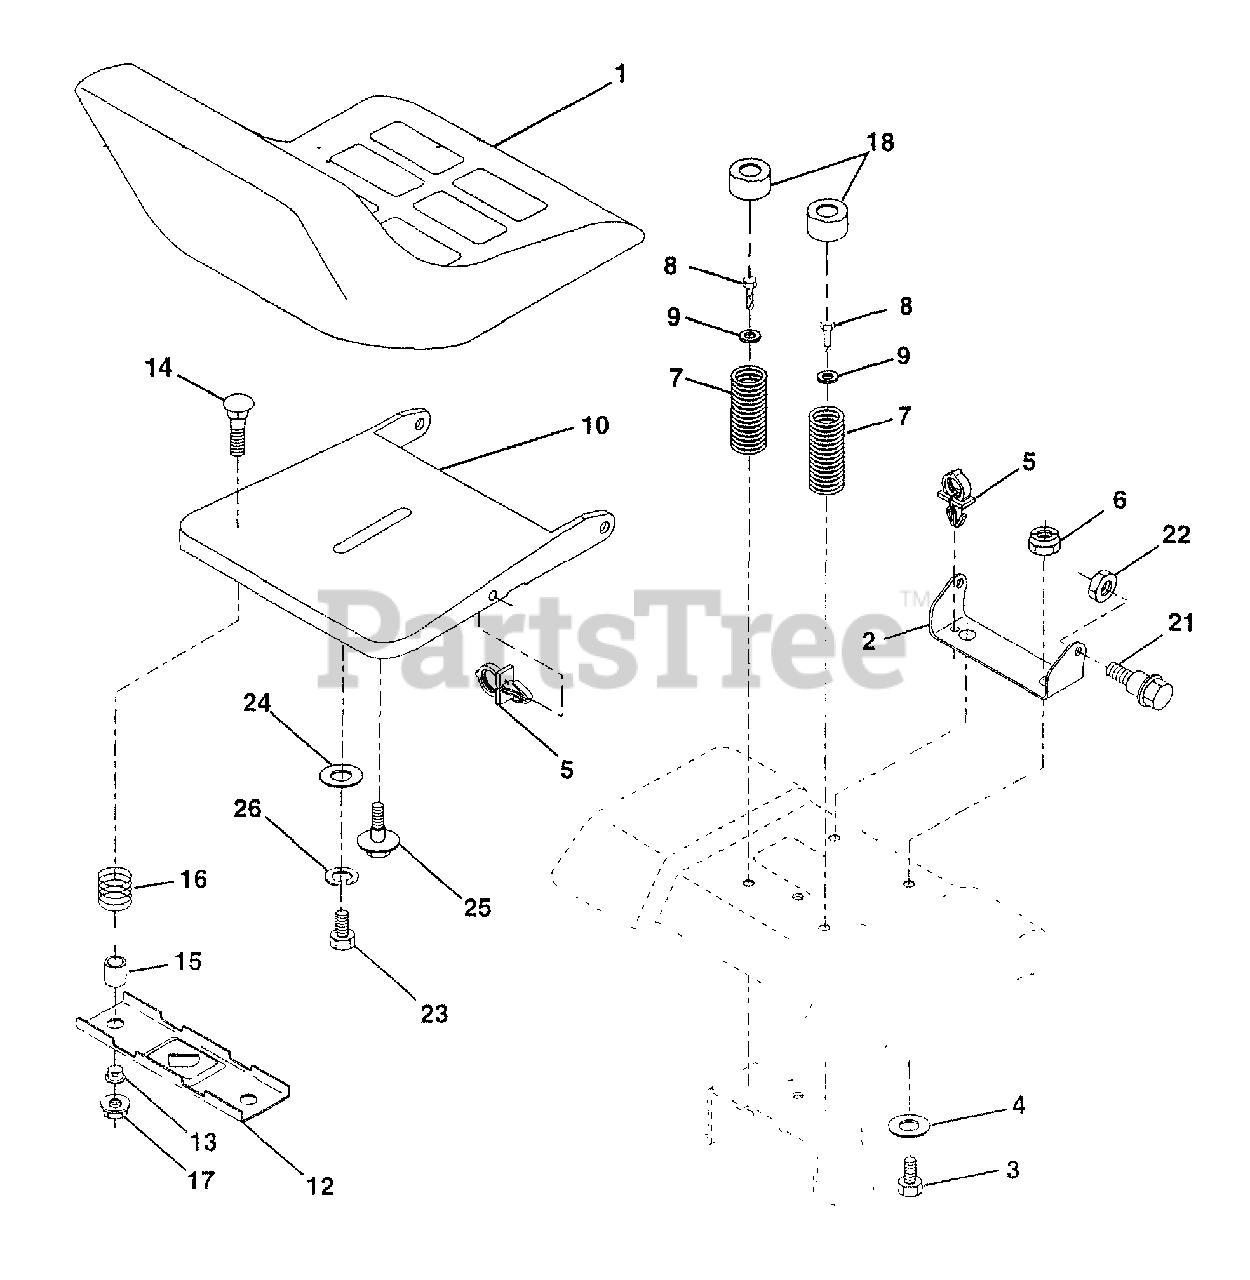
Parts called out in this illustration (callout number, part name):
1	Seat
2	Bracket Pivot Seat 8 720
3	Bolt Fin Hex 3/8-16unc X 1
4	Washer 13/32 X 1 X 10 Ga
5	Clip Push-In
6	Nut Hex w/Ins 3/8-16 Unc
7	Spring Seat Cprsn 2 250 Blk Zi
8	Screw Thdrol 3/8-16 X 1 Ty-tt
9	Washer 13/32 X 1 X 14 Ga.
10	Pan Seat
12	Bracket Mounting Switch
13	Bushing Snap Blk Nyl 50 Id
14	Bolt Rdhd Sqnk 1/4-20x1-3/8
15	Spacer Split 28 x 88 Zinc
16	Spring Cprsn Plate
17	Nut Lock 1/4 Lge Fig Gr 5 Zinc
18	Cap Spring Seat
21	Bolt Shoulder 5/16-18 Unc
22	Nut Hex Lock W/Ins 5/16-18
23	Bolt, Hex Head, Fin 1/2-13 x 7/8 Grade 5
24	Washer 17/32 X 1-3/16 X 12 Ga
25	Bolt Shoulder 5/16-18 X 62
26	Washer Lock
